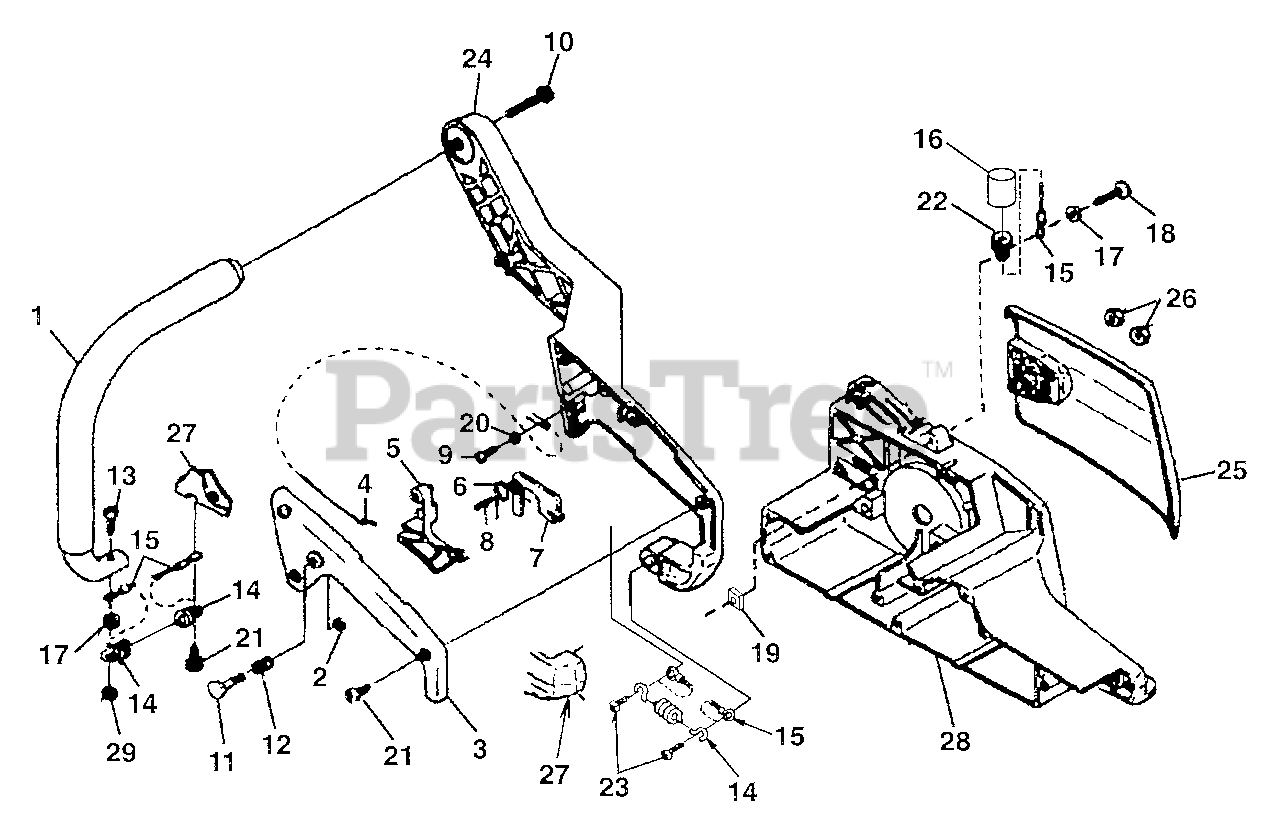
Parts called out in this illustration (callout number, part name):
1	HANDLE BAR
2	RING, RETAINING
3	COVER, REAR HANDLE
4	CABLE, THROTTLE
5	TRIGGER, THROTTLE
6	SPRING, THROTTLE
7	LOCK, THROTTLE
8	PIN, DOWEL
9	SCREW, THREAD FORM (6-19 X 1/2")
10	SCREW, HEX Hd (12-24 X 7/8")
11	PIN, THROTTLE LOCK
12	SPRING, COMPRESSION
13	SCREW, TORX (10-24 X 1/2")
14	SPRING, EXTENSION
15	RETAINER, SPRING
16	SLEEVE, SPRING
17	WASHER, FLAT (#12)
18	SCREW, PAN Hd. (10-24 X 7/8")
19	NUT, SQUARE (#10-24)
20	WASHER, FLAT
21	SCREW, THREAD FORM (8-16 X 5/8")
22	SPRING, EXTENSION
23	SCREW, THREAD FORM (8-16 X 1/2")
24	HANDLE, REAR
25	COVER, DRIVE CASE
26	NUT, HEX
27	HSG., STARTER SIDE
28	ENG. HSG. DRIVE SIDE
29	NUT, HEX
